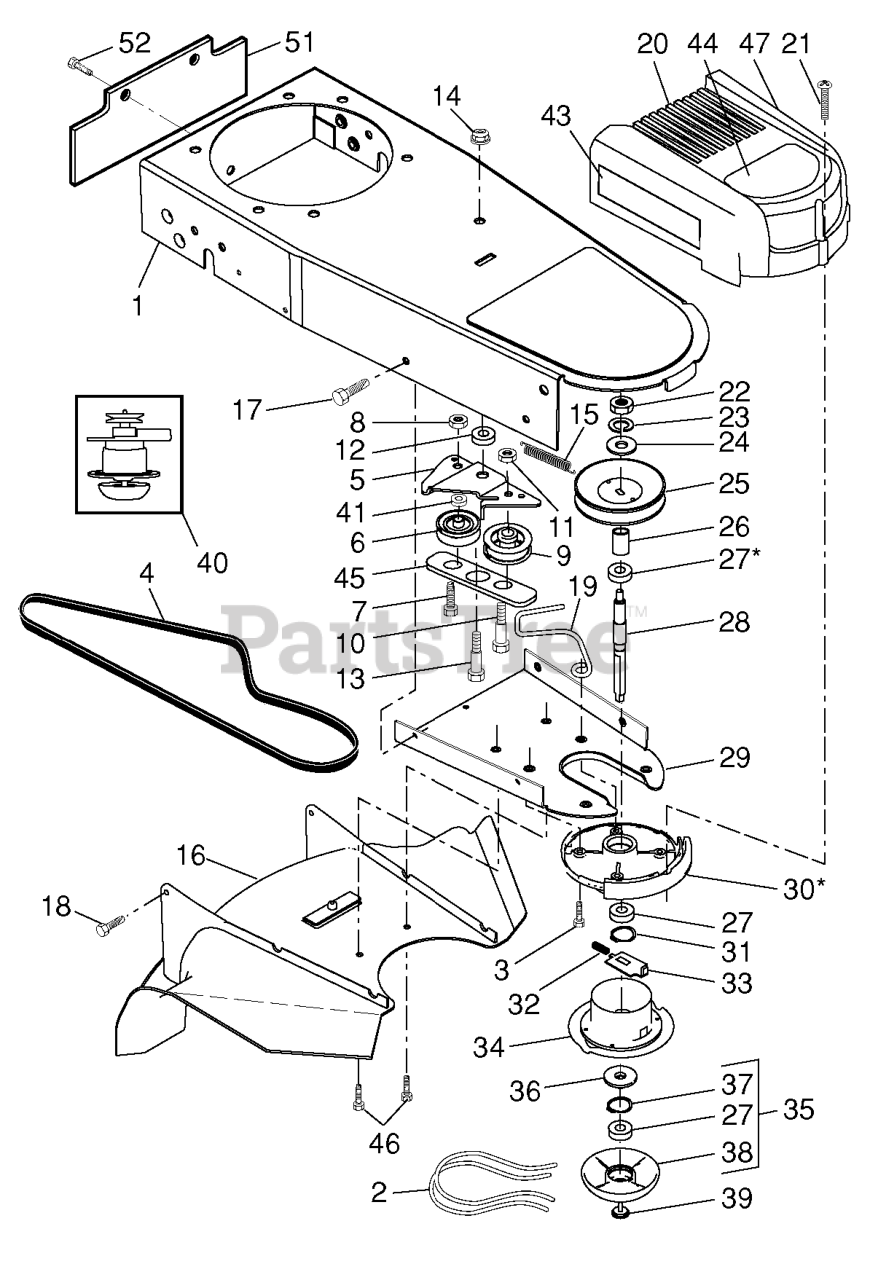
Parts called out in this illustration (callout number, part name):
2	LINE.BUND.18PC
3	BOLT.HEX.HDWSH.5/16-18X1.00
4	BELT-V.STRING TRIMMER.
5	RP.BRACKET.IDLER.TRIMMER.WHEEL
6	PULLEY.V-GROOVE.IDLER
7	BOLT, HEX HEAD 3/8-16 X 1.25
8	LOCKNUT
9	IDLER PULLEY
10	SHOULDER BOLT
11	NUT.CENTERLOCK.5/16-
12	SPACER.IDLER.BRACKET
13	BOLT SHOULDER 3/8 -16X1
14	NUT.HEX.FLANGE.3/8-16.LOCKNUT
15	SPRING.RETURN.WHEELED.TRIMMER
16	DEFLECTOR, BOTTOM
17	SCREW 14-20 X 5/8
19	KEEPER.BELT.STRING.TRIMMER
20	COVER.SUBASM.COVER/IMD.HUSQ
21	SCREW.SLOT.TORX.
22	NUT
23	LOCKWASHER
24	WASHER, FLAT 3/8
25	PULLEY.SPINDLE.WHEELED.TRIMMER
26	SPACER, PULLEY
27	BEARING
28	JACKSHAFT.WHEELED.TRIMMER
29	CHASSIS.COVER.BOTTOM.BLACK
30	SPINDLE HOUSING ASSEMBLY
31	RING, RETAINING, EXTERNAL,
32	SPRING.1.5".COMPRESSION
33	PLATE.LOCKING.WHEELED.TRIMMER
34	CARRIER PLATE ASSEMBLY
35	MOW BALL ASSEMBLY
36	COVER, BEARING
37	RING, RETAINING, INTERNAL,
38	MOW BALL
39	BOLT, MOW BALL
40	ASM.ADJUSTABLE.SPINDLE.WHLD.TR
41	SPACER (2 2MC)
43	DECAL.TRIMMER.WHEELED.HEIGHT
44	DECAL.BADGE.55MM.CROWNH.HUSQ
45	BRACKET.BELT.KEEPER.BLACK
47	DECAL.TRIMMER.WHEELED.INSTRUCT
51	SKIRT.REAR.WHEELED.TRIMME(3 2)
